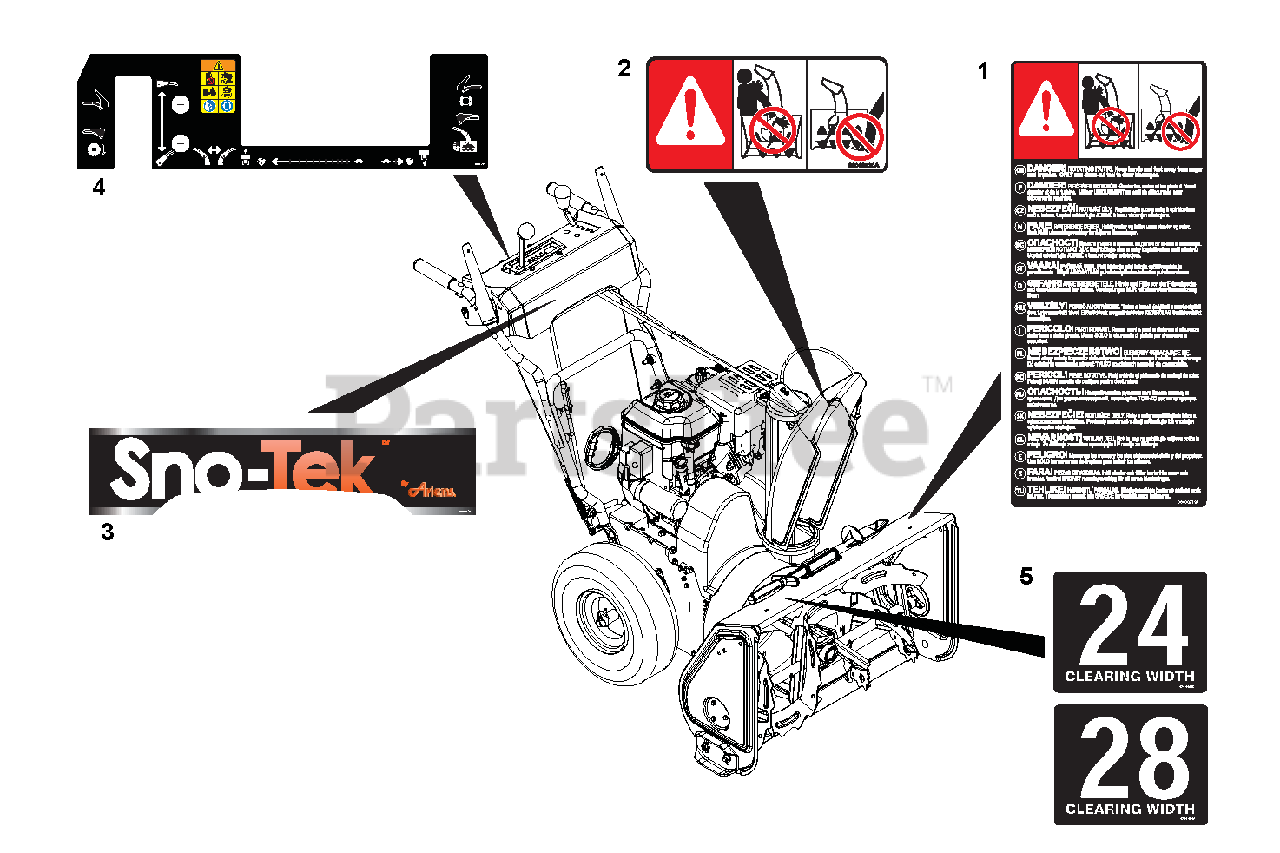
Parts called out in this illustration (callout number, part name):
1	DECAL, DANGER - ROTATING PARTS
2	DECAL, DANGER
3	DECAL, DASH - SNO-TEK
4	DECAL,CONTROL - COMPACT REMOTE
5	DECAL, HOUSING SNO-TEK 24
